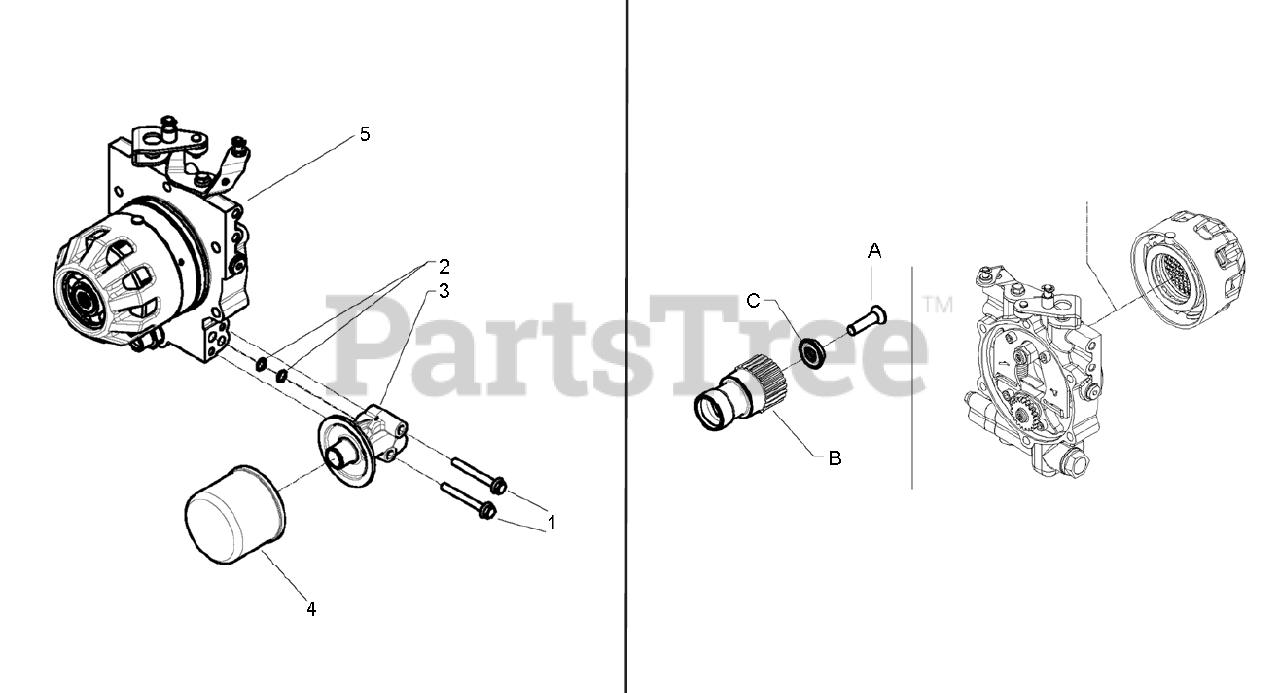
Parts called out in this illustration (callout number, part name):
2	O-RING 108 (8,73X1,78)
3	CONNECTION
4	FILTER
5	HYDRAULIC BLOCK GX390
A	BOLT 3/8-24X1.25"
C	WASHER
